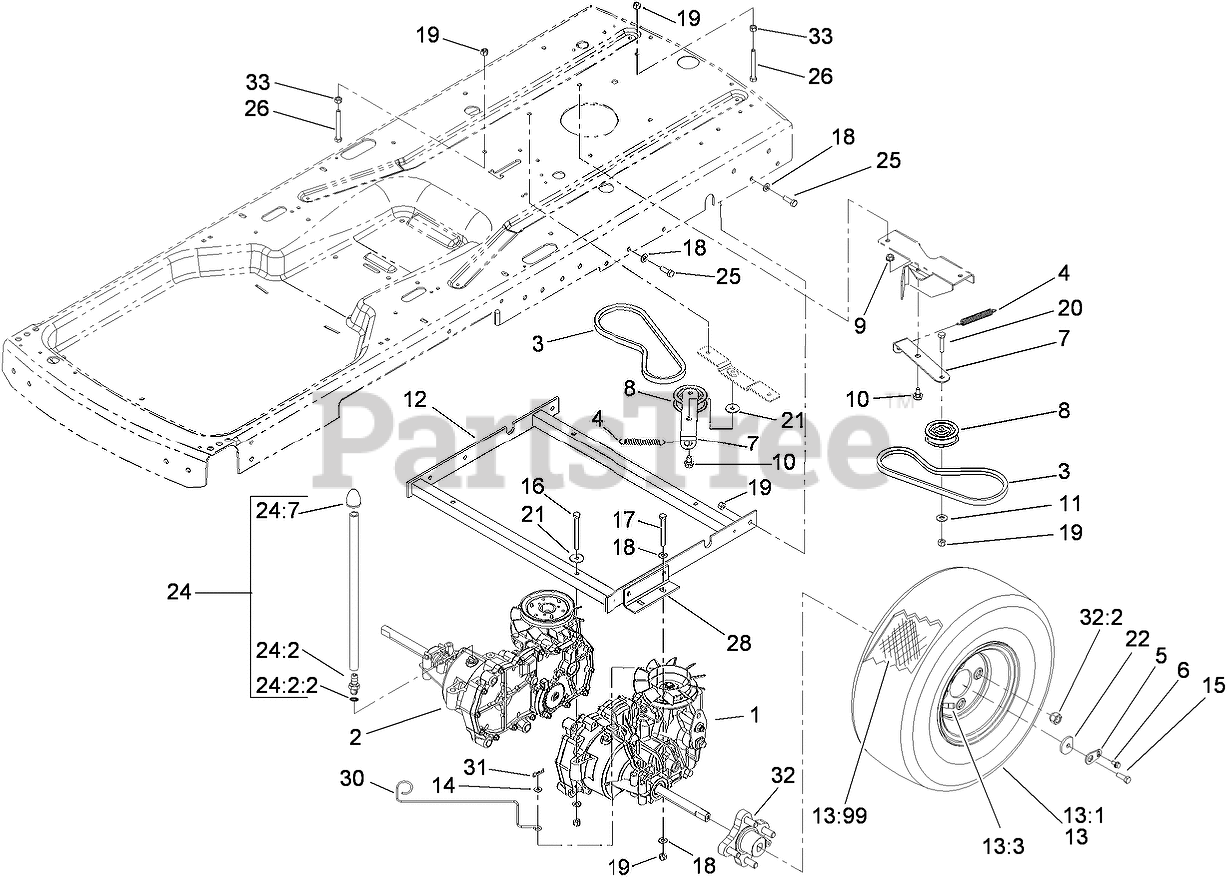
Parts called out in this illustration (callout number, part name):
1	TRANSAXLE-HYDRO, LH
2	TRANSAXLE-HYDRO, RH
3	V-BELT
4	SPRING
5	TAB-LOCKING
6	SCREW-HHF
7	ARM-IDLER
8	PULLEY-IDLER
9	NUT-HF
10	BOLT-SHOULDER
11	WASHER-FLAT
12	HYDRO MOUNT ASM
13	REAR WHEEL ASM
13:3	STEM-VALVE
14	WASHER-FLAT
15	SCREW-HH
16	SCREW-HH
17	SCREW-HH
18	WASHER-PLAIN
19	NUT-LOCK, NI
20	SCREW-HH
21	WASHER-PIVOT
22	WASHER-WHEEL
24	VENT HOSE ASM
24:2	FITTING ASM
24:2:2	O-RING
24:7	CAP VENT ASM
25	SCREW-HH
26	SCREW-HH
28	SUPPORT-HYDRO
30	ROD-BYPASS
31	PIN-COTTER
32	HUB ASM
32:2	NUT-LUG
33	NUT-HEX
